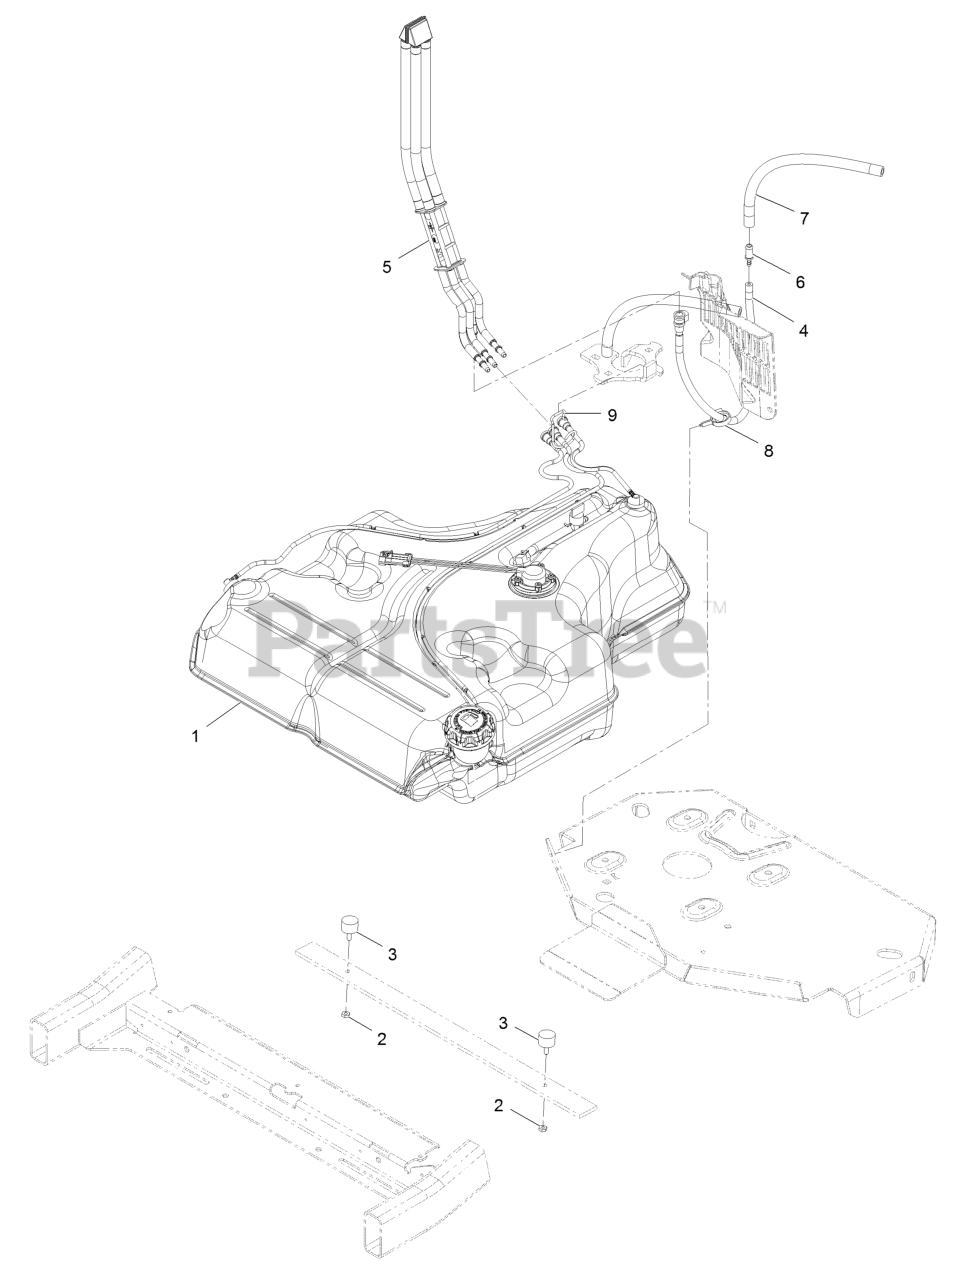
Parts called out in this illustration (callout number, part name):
2	NUT-JAM
4	HOSE ASM
5	FUEL MANIFOLD VENT ASM
6	FITTING-STRAIGHT
7	HOSE-FUEL
8	CLAMP-HOSE
9	RETAINER-LINE, VAPOR
